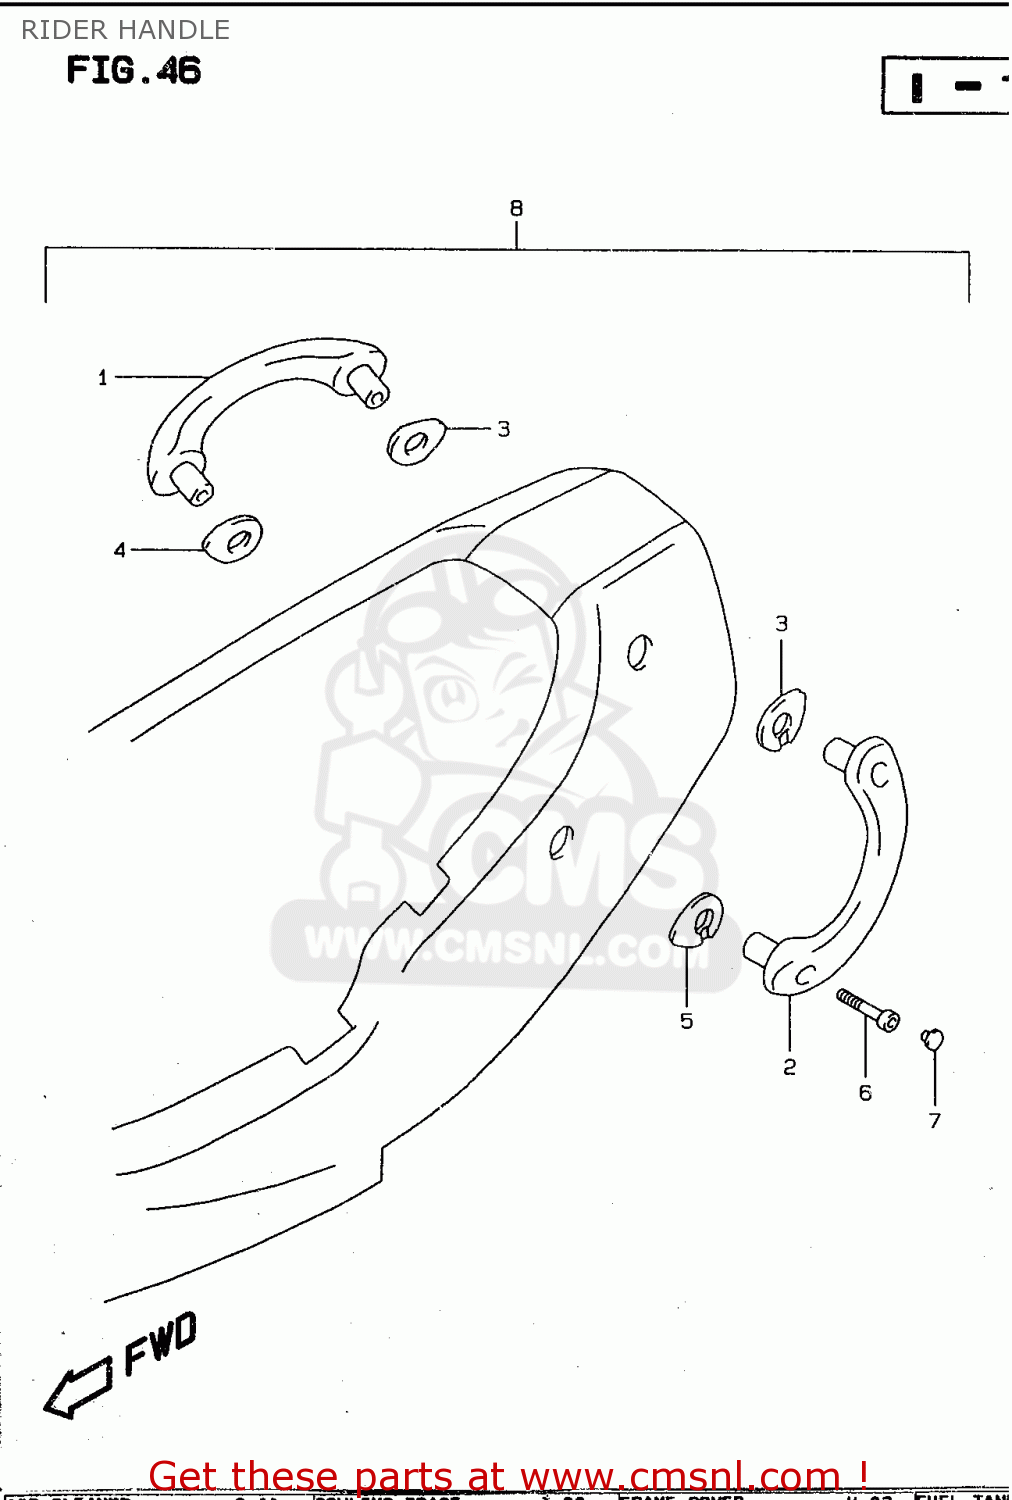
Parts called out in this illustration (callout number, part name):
1	HANDLE,PILLION RIDER,R
2	HANDLE,PILLION RIDER,L
3	CUSHION,PILLION HANDLE UPR
4	CUSHION,PILLION HANDLE LWR,R
5	CUSHION,PILLION HANDLE LWR,L
6	BOLT
7	CAP(OD:14.5)
8	HANDLE SET,PILLION RIDER(BLACK
